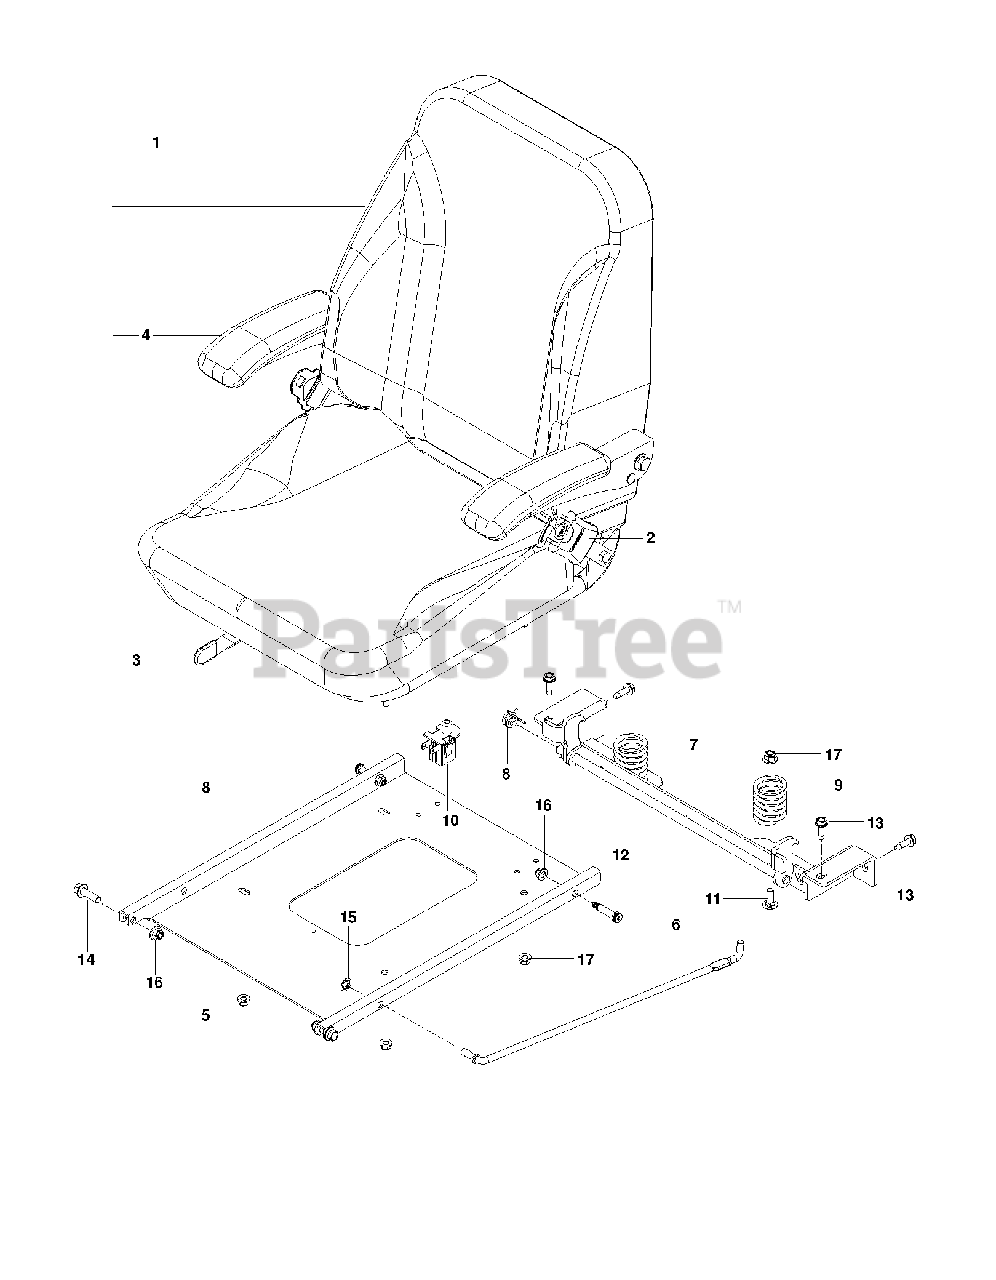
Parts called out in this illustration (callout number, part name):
1	SEAT ASSY
3	TRACK KIT
4	ARMREST, LT
5	PAN, SEAT, BLACK
6	ROD, SEAT
7	LATCH, SEAT, BLK
8	SPRING, TORSION
9	SPRING, SEAT
10	SEAT SWITCH
11	RHSNB 3/8C X 1
12	BOLT, SHOULDER 3/8 X 1.25
16	NUT 3/8-16 HEX FLG NYLOC ZD
17	5/16-18 NYLOC FLANGE NUT
